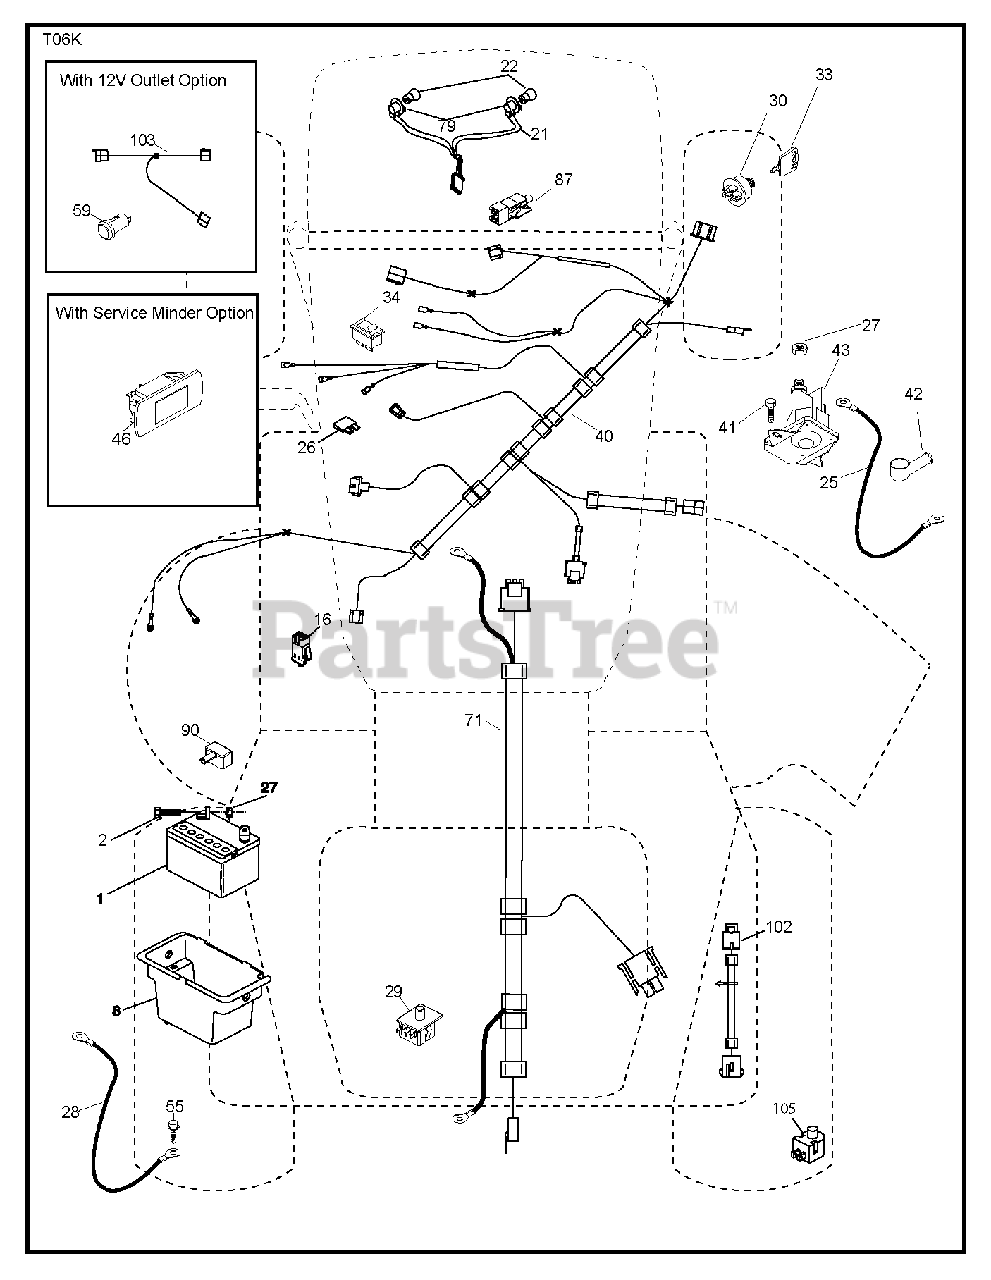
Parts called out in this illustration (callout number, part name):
1	REPL BY 532 12 38-99
2	BOLT.HEX.1/4.X.3/4.DICHROMATE
8	BOX.BATTERY.MNT.REAR.L
16	SWITCH INTERLOOK PUSH-IN
21	HARNESS.W/LIGHT SOCKET
22	LIGHTBULB
25	CABLE.STARTER.6GA.BL/RED.14.
26	FUSE 20AMP
27	NUT
28	CABLE.BLACK.18"REAR.BA
29	SWITCH.SEAT.DP W/RAMPS
30	SWITCH.IGN.DELTA.W.LGH.ROS
33	KEY.CHAIN.BLISTER.PACK.CRF.INT
34	SWITCH LT
40	HARNESS IGN. DASH
41	SCREW
42	TERMINAL COVER
43	SOLENOID.W/BRASS.PLUNGER
55	SCREW 5/16"
71	HARNESS.CHASSIS.TEX.8AWG
79	BULB HOLDER ASM.
87	SWITCH.INTRLCK.CLUTCH.
90	COVER.TERMINAL.BATTERY
102	HARNESS.PIGTAIL.VAR.SD.FC
105	REVERSE SWITCH
